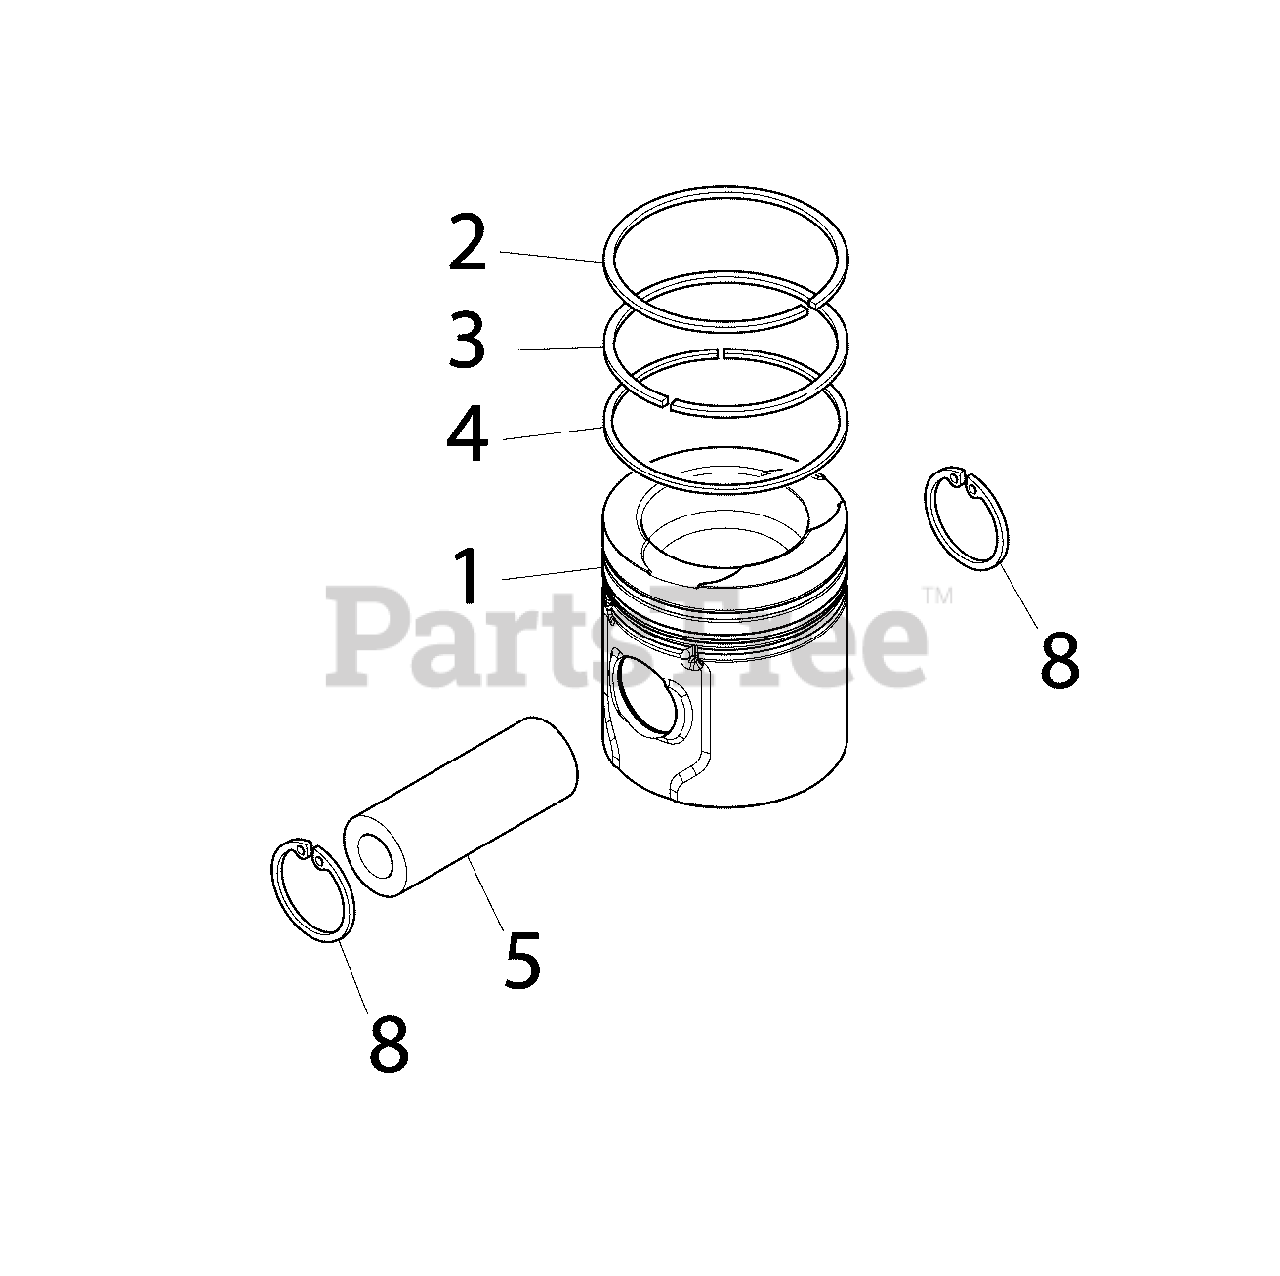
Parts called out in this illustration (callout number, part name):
1	* PISTON
2	* TOP RING *
3	* 2ND RING *
4	* OIL RING *
5	* PIN, PISTON
8	* RING, SNAP
